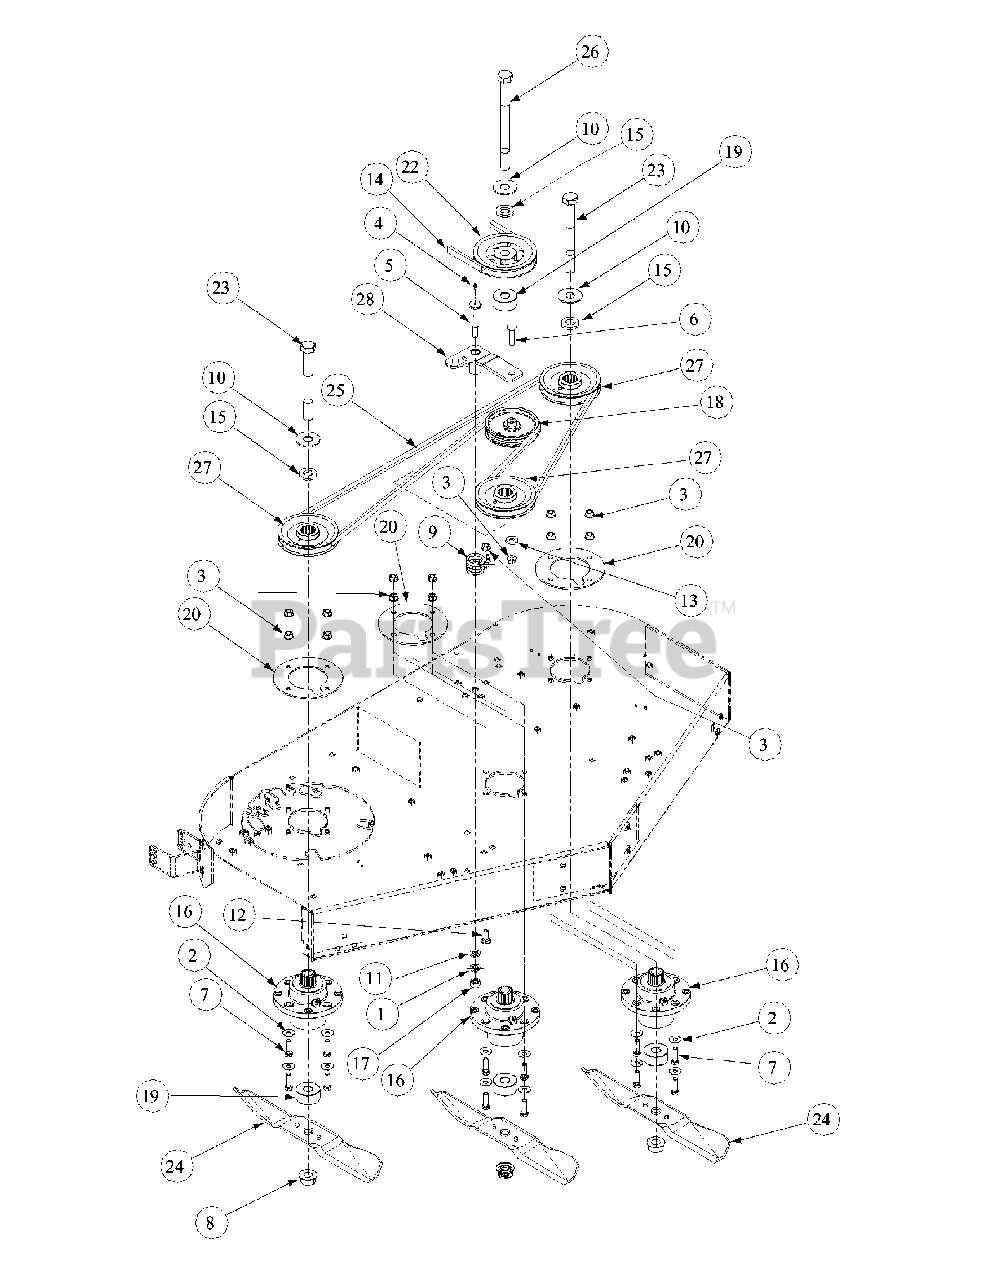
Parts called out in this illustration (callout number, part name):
1	Lock Washer, 7/16
2	3/8 Flat Washer
3	Flange Lock Hex Nut, 3/8-16
4	Grease Fitting, 1/4-28 x 3/16
5	Shoulder Screw, 7/16-14
6	Hex Carriage Screw, 3/8-16 x 1.75
7	Hex Cap Screw, 3/8-16 x 1-1/2
8	Hex Flange Nut, 3/4-16
9	Idler Torsion Spring
10	Flat Washer, .781 ID x 2.00 OD x .105
11	Flat Washer, .469 ID x .875 OD x .105
12	Carriage Bolt, 3/8-16 x 1
13	Flat Washer, .406 ID x 1.0 OD x .105
14	Belt, B Section x 65.04
15	Spacer, .812 ID x .268 Lg
16	Spindle Assembly
17	Hex Nut, 7/16-14
18	Flat Pulley With Flanges
19	Spacer, .760 ID x 2.000 OD x .092
20	Caster Spindle Support Plate
22	Cast Pulley, 5.25 OD
23	Hex Cap Screw, 3/4-16, 7.00
24	Blade, 17.0 Hi-Lift, .756 ID
25	Belt, A Section x 105.3
26	Hex Cap Screw, 3/4-16 x 9.00
27	Cast Pulley, 4.65 OD
28	Idler Bearing Arm Assembly
